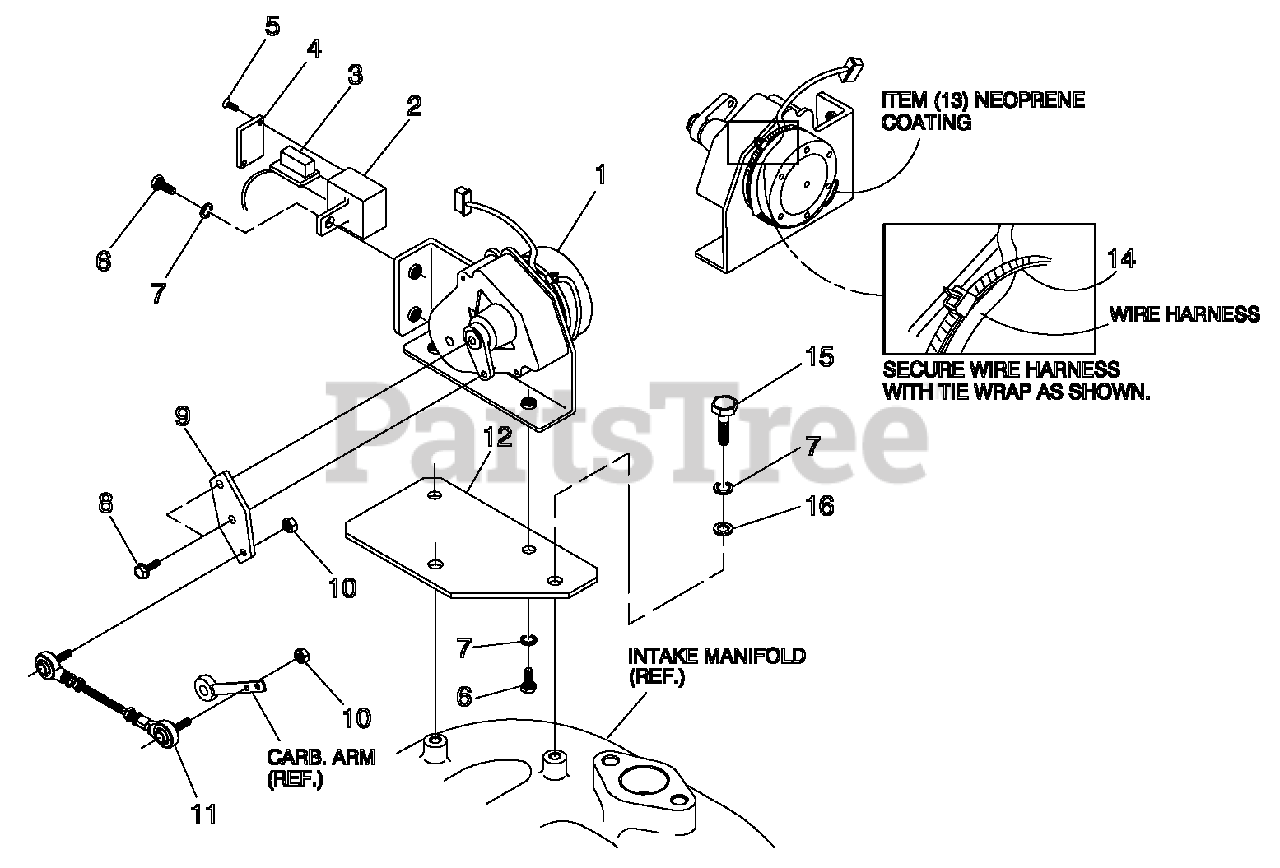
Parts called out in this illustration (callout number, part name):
1	ASM MOTOR STEPPER
2	HOUSING GOVERNOR CONNECTOR
3	CONNECTOR INTERFACE ASSEMBLY
4	COVER CONNECTOR HOUSING
5	SCREW FHM #2 X 5/8 SELF TAP
6	SCREW HHC M6'1.0 X 10 G8.8
7	WASHER LOCK M6'1/4
8	SCREW TAP HWH #6'25 X 3/8 ZINC
9	LEVER STEPPER MOTOR
10	NUT LOCK HEX #10'32 NYL INS
11	ASSEMBLY CARBURATOR LINKAGE
12	BRACKET STEPPER MOTOR
13	LIQUID NEOPRENE
14	TIE WRAP 7.4"X.19" BLK UL
15	SCREW HHC 1/4'20 X 1/2 G5
16	WASHER FLAT 1/4 ZINC
